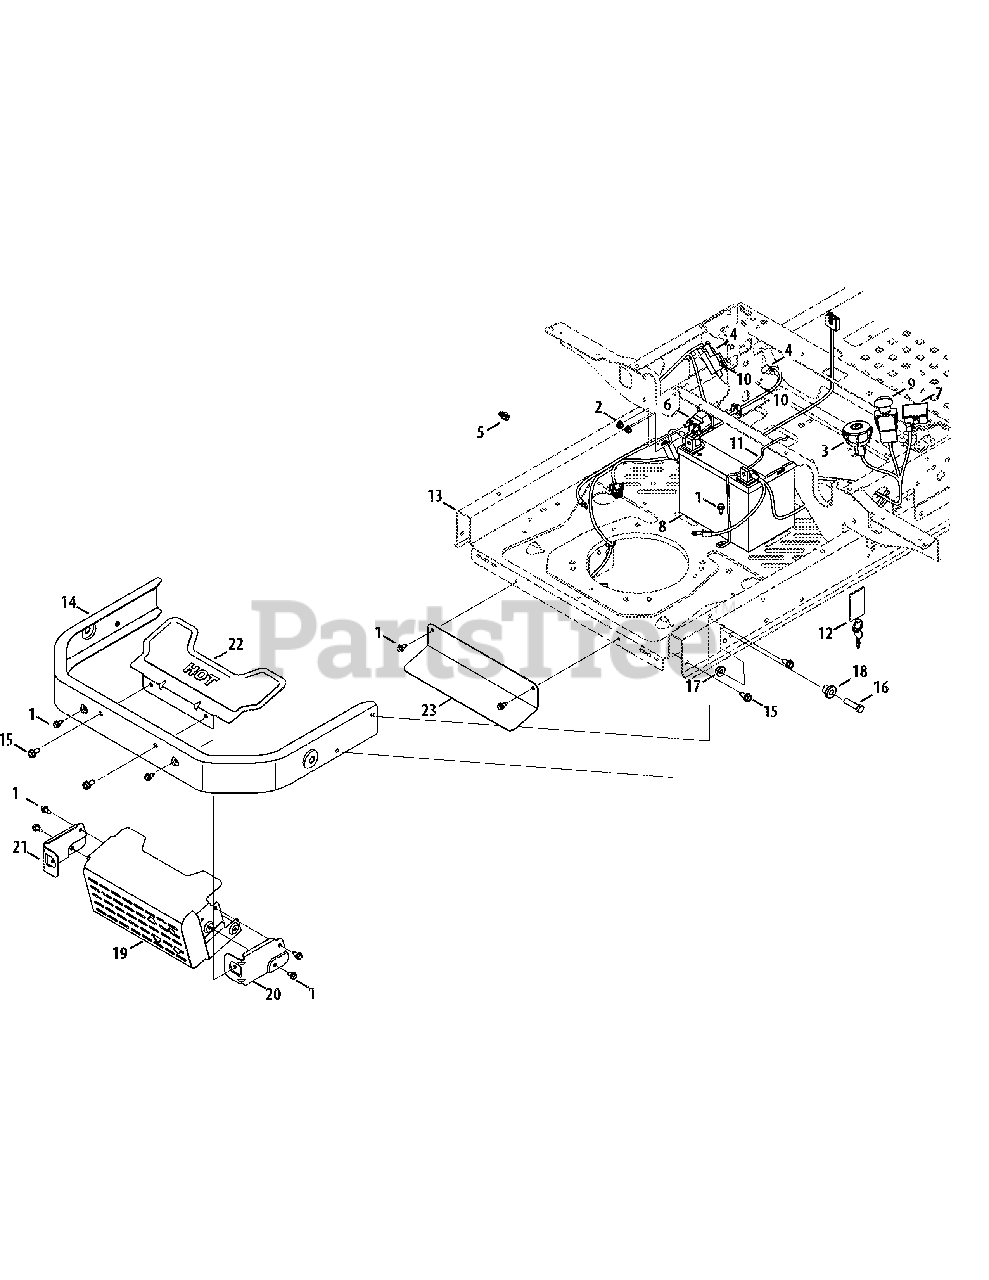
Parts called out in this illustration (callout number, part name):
1	Hex Washer Screw, 1/4-20 x .375
2	Flange Lock Nut, 1/4-20
3	Key Switch
4	Interlock Switch
5	Harness
6	Solenoid
7	Hour Meter/Service Minder
8	Battery
9	PTO Switch
10	Shoulder Screw
11	Battery Retainer
12	Key
13	Frame
14	Bumper
15	Hex Washer Screw, 5/16-18 x .750
16	Hex Screw, 3/8-16 x 1.25
17	Flange Lock Nut, 3/8-16
18	Shoulder Spacer, .38 x 1.0 x .70
19	Muffler Shield Assembly
20	RH Muffler Shield Mount Bracket
21	LH Muffler Shield Mount Bracket
22	Muffler Shield
23	Lower Heat Shield
